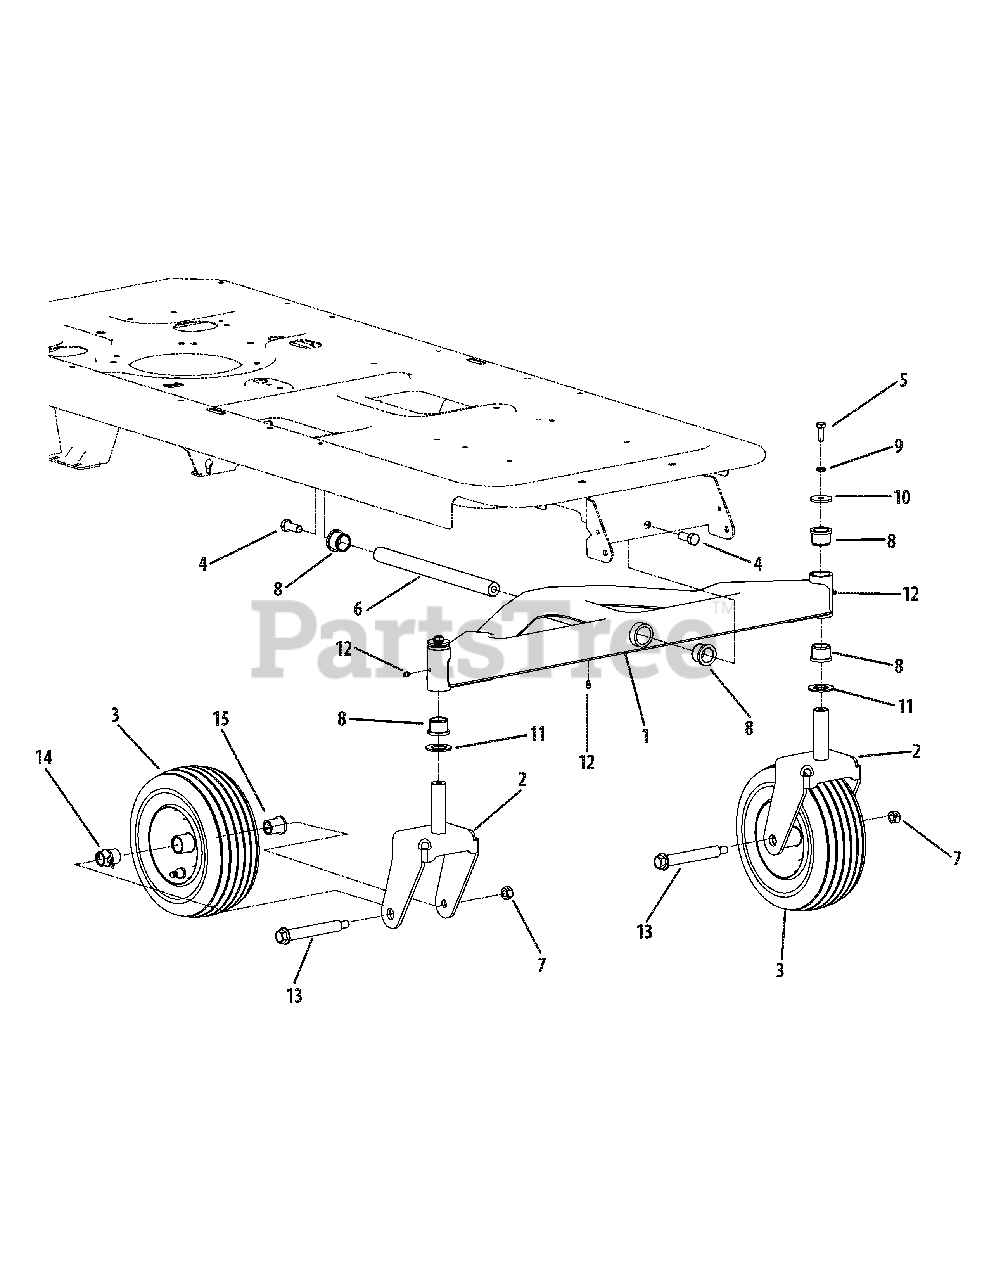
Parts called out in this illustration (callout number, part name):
1	Front Pivot Axle
2	Castor Wheel Bracket
3	Wheel Assembly, 11.0 x 4.0 x 5.0
4	Hex Lock Screw, 1/2-13 x 1.25
5	Hex Cap Screw, 3/8-16 x 1.0
6	Axle Shaft
7	Hex Lock Nut, 1/2-13
8	Flange Bearing, 1.0 x 1.246
9	Lock Washer, 3/8
10	Flat Washer, .39 x 1.5 x .134
11	Flat Washer, 1.0 x 1.75 x .107
12	Lube Fitting, 3/16
13	Shoulder Screw, 7/16-14 x .75 x 4.75
14	Flange Bearing, .76 x 1.0 x 1.2
15	Flange Bearing, .76 ID w/Lube Ftg.
